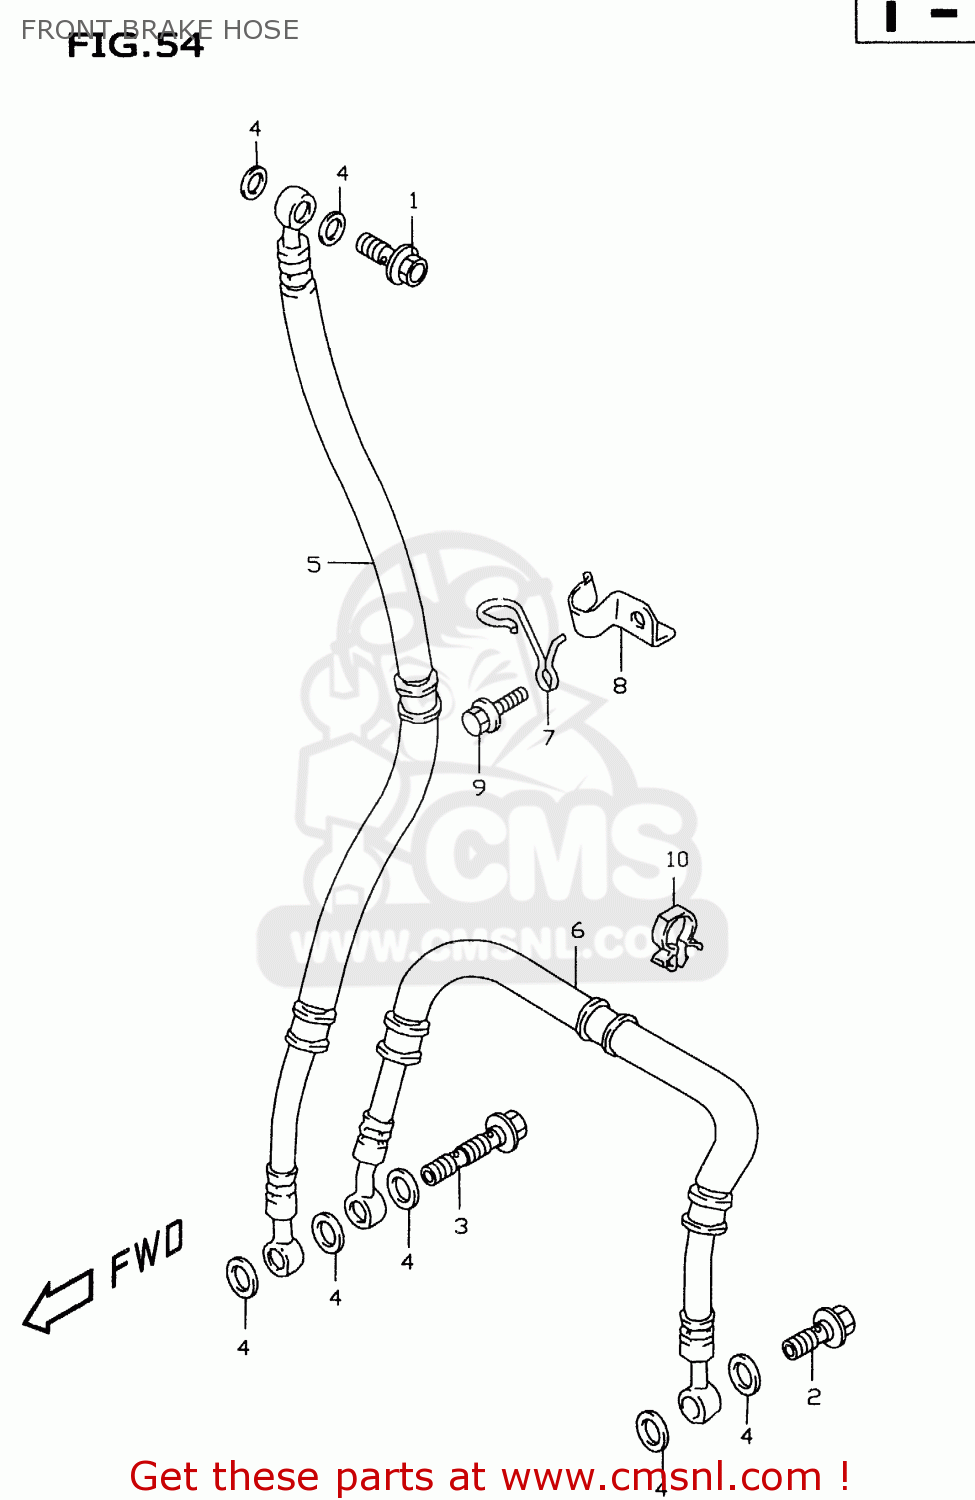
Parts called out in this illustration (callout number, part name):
1	BOLT UNION
2	BOLT UNION
3	BOLT UNION
4	WASHER(10X15X1.5)
5	HOSE,FR BRAKE NO.1
6	HOSE,FR BRAKE NO.2
7	GUIDE,FRONT BRAKE HOSE
8	CLAMP,FR BRAKE HOSE UPR
9	BOLT
10	CLAMP
